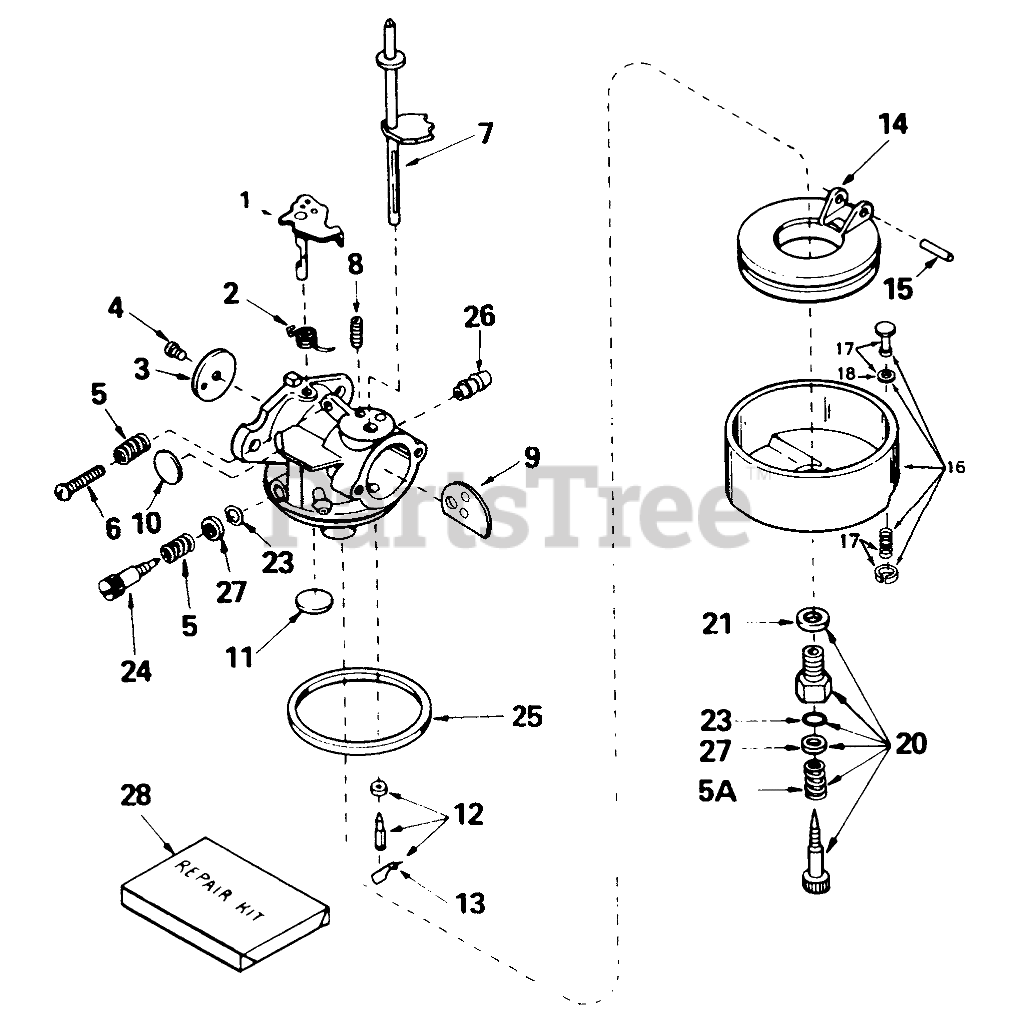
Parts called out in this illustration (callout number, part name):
1	Shaft/Lever-Throttle
2	Spring-Return, Throttle
3	Shutter-Throttle
4	Screw-Shutter
5	Spring-Tension
6	Screw-Throttle Crack Screw / Idle Speed
7	Shaft-Choke
8	Spring-Positioning, Choke
9	Shutter-Choke
10	Plug-Welch, Idle Mixture Well
11	Plug-Welch, Atmospheric Vent
12	Inlet Needle-Seat & Clip (Incl. Ref. #13)
13	Clip-Spring
14	Float
15	Shaft-Float
16	Bowl-Assembly (Incl. Ref. #17 & 18)
17	Drain Assembly-Bowl (Incl. Ref. #18)
18	Gasket-Plunger, Drain
20	Screw Adjustment Assembly (Incl. Ref. #5A, 21, 23, & 27)
21	Washer-Bowl Nut
23	"O"Ring
24	Screw-Idle
25	O Ring-Bowl, Float
26	Fitting-Fuel
28	Kit-Repair
